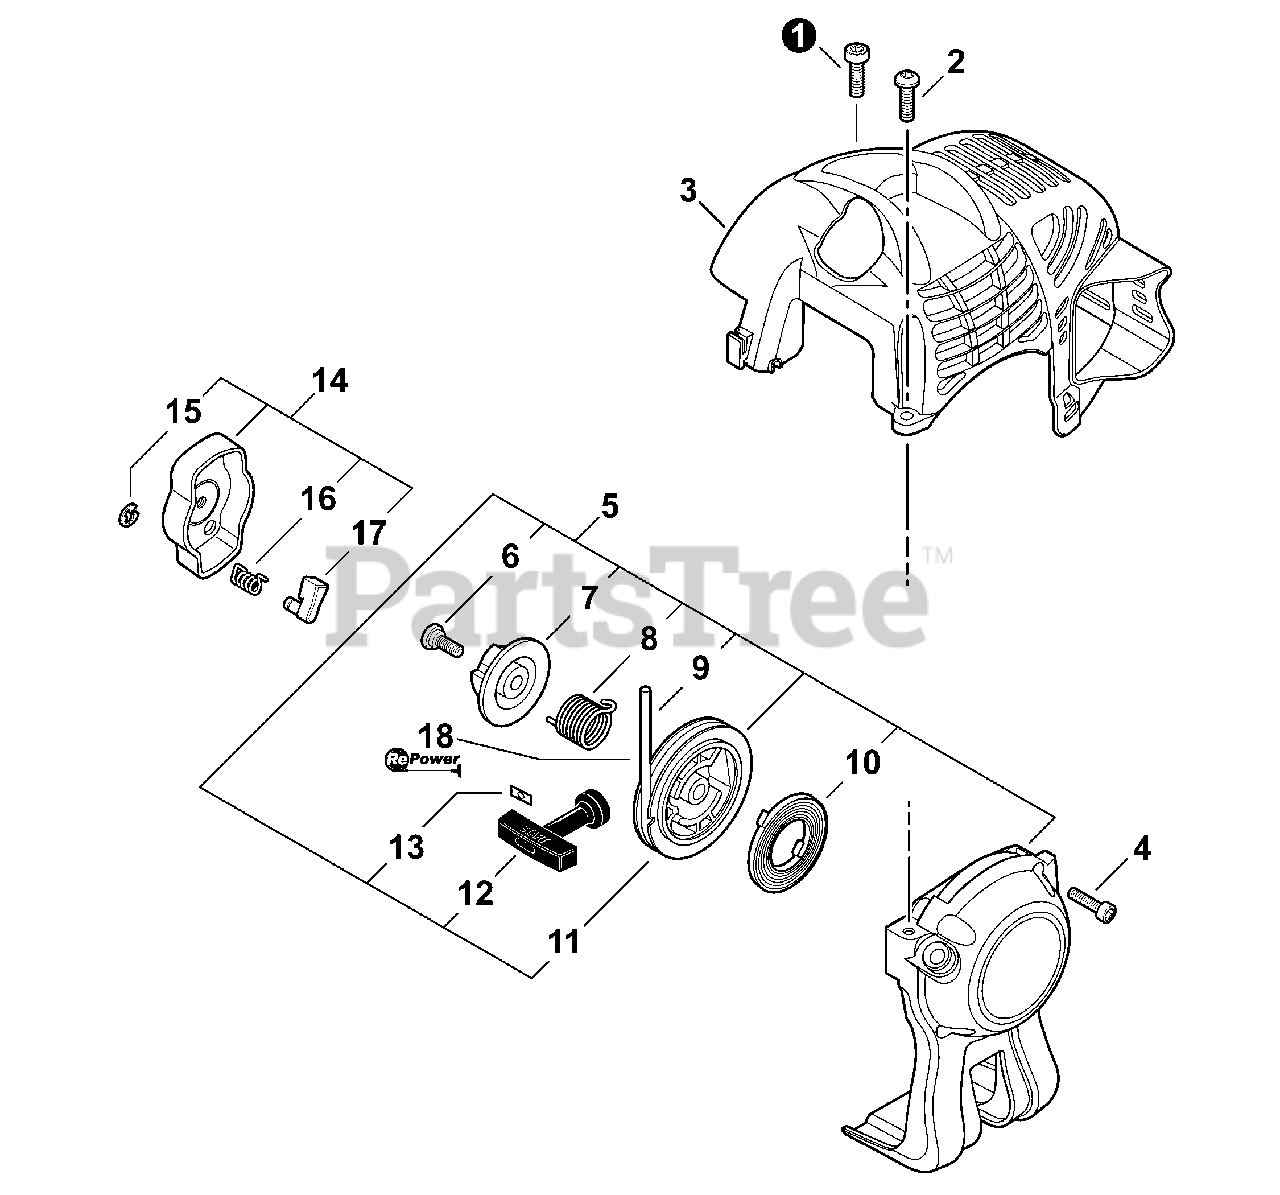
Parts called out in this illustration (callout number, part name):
1	SCREW - 5×16
2	SCREW - 5×16
3	COVER, ENGINE
4	SCREW - 4×16
5	STARTER ASSY
6	SCREW
7	PLATE, CAM
8	SPRING, DAMPER
9	ROPE, STARTER - 3×700
10	SPRING, REWIND
11	REEL, ROPE
12	GRIP, STARTER
13	RETAINER, ROPE
14	STARTER PAWL ASSY
15	RING, RETAINING - 4
16	SPRING, RETURN
18	ROPE, STARTER - REPOWER BULK
